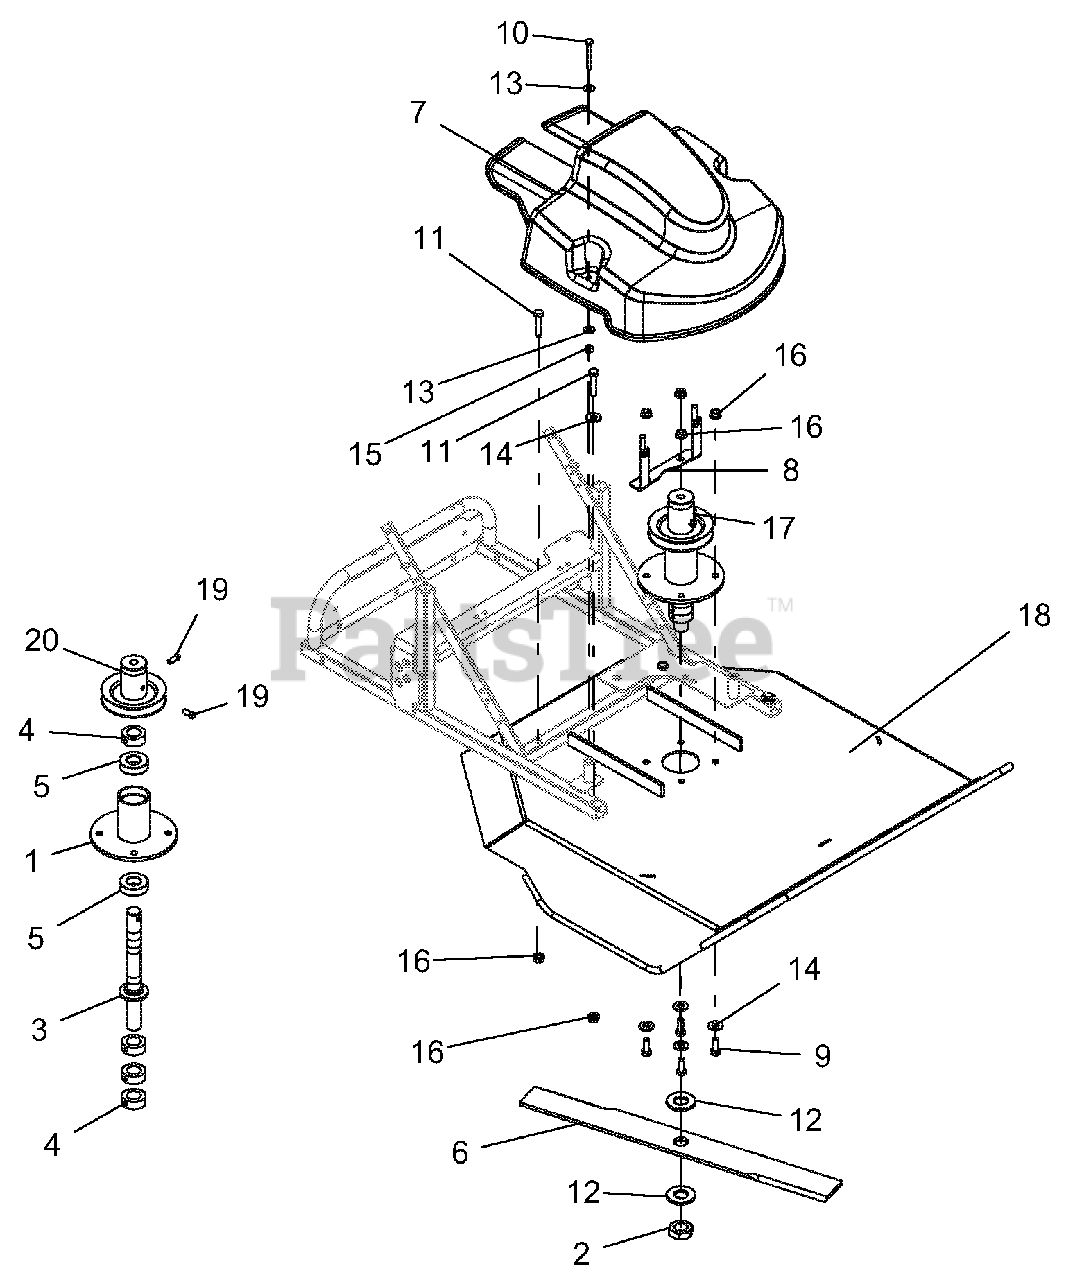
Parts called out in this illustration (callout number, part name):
1	WMT-SPINDLE, HW MOWER 17304K
2	JAM NUT 1-14 NF 15614
3	WMT-SPINDLE SHAFT, HWM 18876K
4	LOCKING COLLAR 1IN 50022213
5	BEARING 1.00 ID X 2 50019553
6	BLADE,BUSH MOWER 24"
7	COVER, PLASTIC BELT-HIGH WHEEL
8	WMT-HWM SPINDLE BELT FINGER
9	@BLT-HEX .38-16X1.00 GR5 YWZC
10	@BLT-HEX .25-20X2.25 GR5 YWZC
11	@BLT-HEX .38-16X1.75 GR5 YWZC
12	1"USS WASHER HARD NO PLA 33852
13	@WSHR-FL-STL.312X.734X.065 YWZ
14	@WSHR-FL-STL.438X1.00X.083 YWZ
15	@NUT-LK-NYL .250-20 YWZC
16	@NUT-LK-TOP-FLG .38-16 YWZC
17	KIT, DECK SPINDLE ASSY, HWM
18	DECAL, ARIENS BRUSH DECK W/
19	SCR-SET .31-18X.75 SQHCUP HT
20	DOUBLE BLADE SHAFT PULLEY
